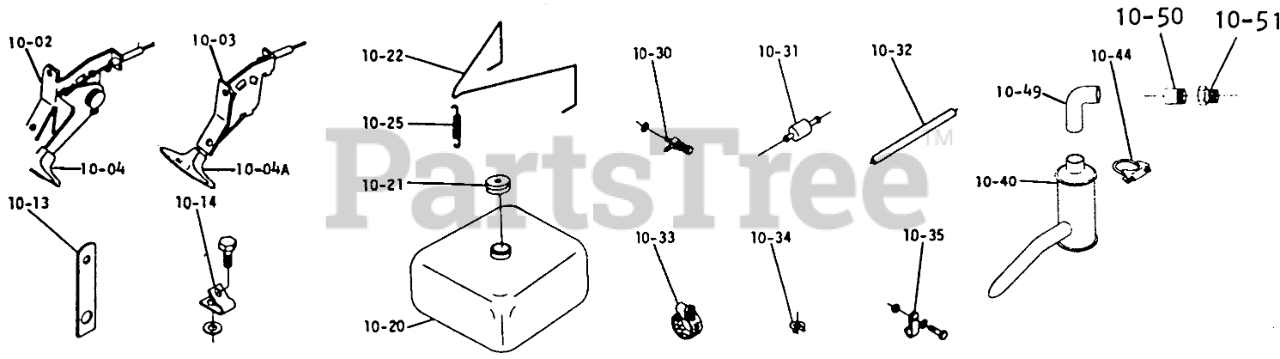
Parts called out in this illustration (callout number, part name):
10-03	THROTTLE CONTROL
10-03	#10-24 Kep-Nut
10-04	KNOB-CHOKE
10-04A	KNOB-THROTTLE
10-14	THROTTLE CONTROL CLP
10-14	Bolt 1/4-20 x 3/8
10-14	Bolt, 1/4-x 1/2
10-14	Nut-Nylok
10-22	HOLD DOWN WIRE
10-30	S/A FUEL VALVE
10-32	Fuel Line
10-32	Hose-Fuel-Pump to Carb 5.5
10-35	Bolt, 5/14-18 x 1 1/4
10-35	Washer
10-35	Nut-Nylok
10-40	MUFFLER
10-44	ASSY-MUFFLER CLAMP
